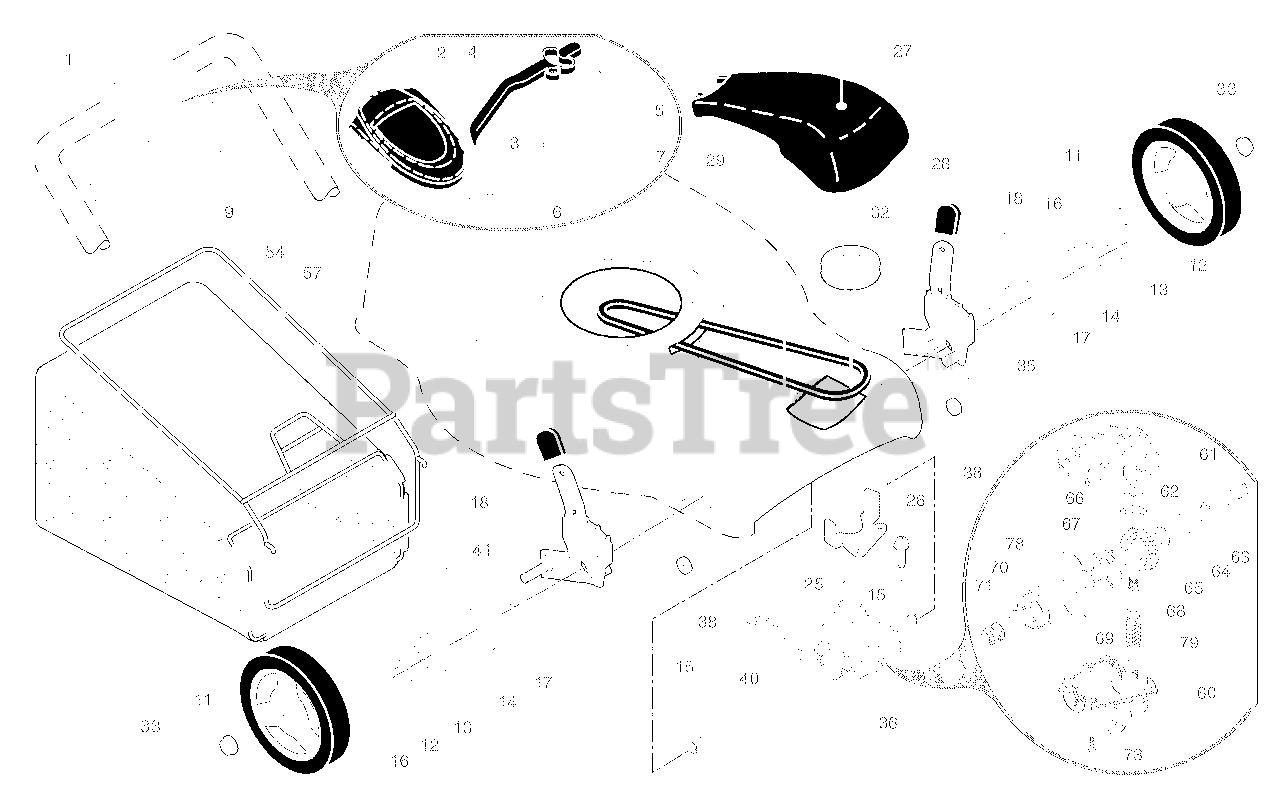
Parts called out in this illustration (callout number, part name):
1	Drive Control Assembly
2	Cover, Drive Control, Upper
4	Lever, Drive Control
5	Cover, Drive Control, Lower
7	Mounting Bracket, Drive Control
9	Cable, Drive
11	Wheel & Tire Assembly
14	Dust Cover
15	Pawl, Drive
16	Washer 1/2 x 1-1/2 x .134
17	Bearing, Wheel Adjuster
18	Selector Knob
25	Belt Keeper
26	Screw, Hi-Lo Thread
27	Pan Head Tapping Screw #10-24 x 2-3/4
28	Drive Cover
32	Drive Pulley
33	Locknut, Hex
35	Kit, Wheel Adjuster, LH
36	Gearcase Assembly, Complete
38	Locknut, Hex 1/4-20
41	Kit, Wheel Adjuster, RH
54	Grassbag Assembly
57	Frame, Grassbag
60	Case, Lower
61	Case, Upper
62	Shaft, Output
63	Seal, Output Shaft
66	Seal, Worm Shaft
67	Bearing, Ball
68	Gear, 28 Teeth
69	Fixed Dog Clutch
70	Pin
71	Movable Dog Clutch
73	Screw, Case
78	Spring, Leaf
79	Shaft, Worm
